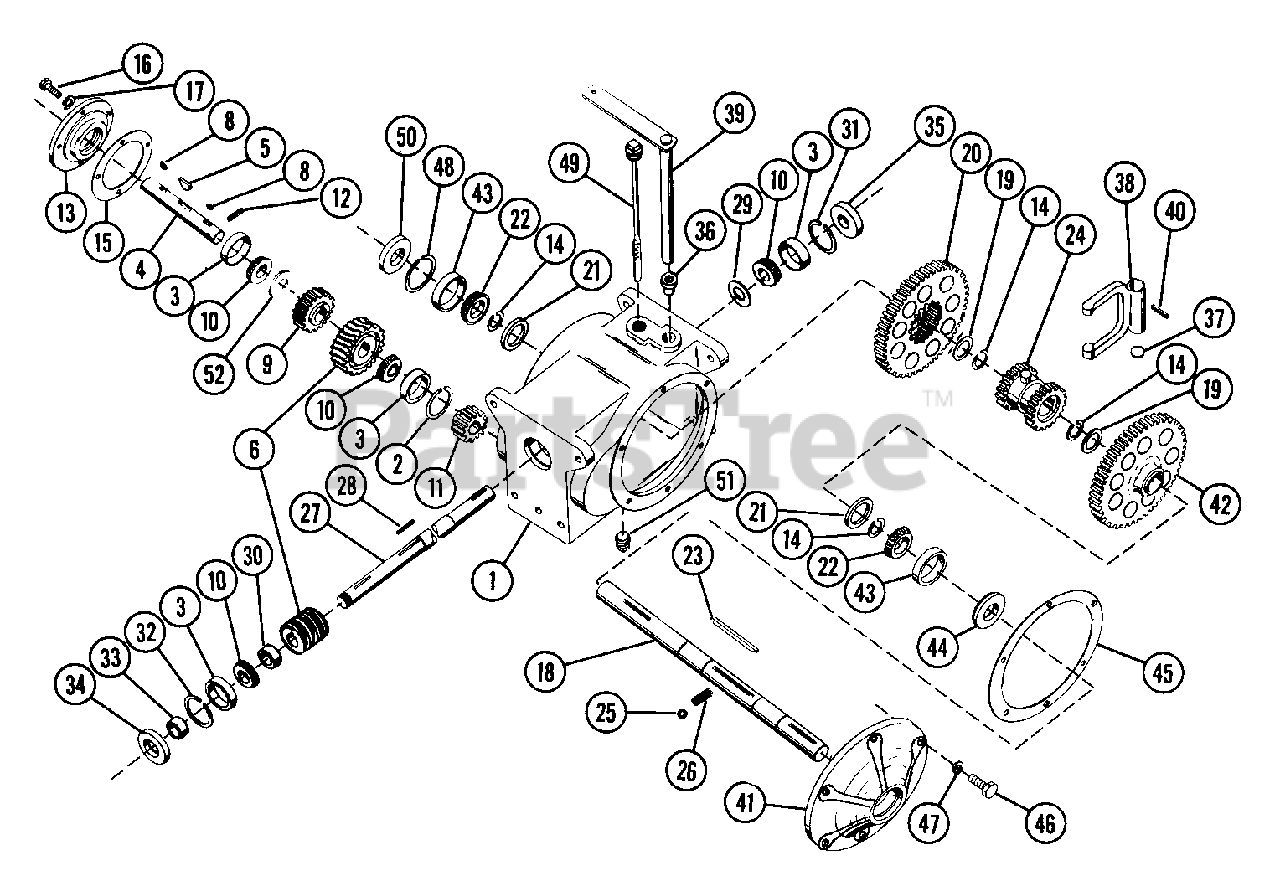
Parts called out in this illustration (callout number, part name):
1	TRANSMISSION CASE
2	RG-RTNG-INT 1.781X.062
3	BRG-CUP 1.781X.475
4	PINION SHAFT
5	KEY-WDRF .188X.875X.375 SAE11
6	50100& WORM GEAR ASSEMBLY TRAN
8	KEY-WDRF .188X.75X.313 SAE 9
9	HIGH PINION
10	BRG-CONE .750X.61
11	LOW PINION
12	PIN-ROLL .188X1.00
13	PINION FLANGE
14	RG-RTNG-EXT .984X.062
16	BLT-HEX .31-18X.75 PL GR2
17	WSHR-LK .312X.097 PL HVY
18	AXLE SHAFT
20	HIGH GEAR
21	GEAR SPACER 1.75 X 1.31 X .5
22	BRG-CONE 1.0X.58
23	KEY-FTHR .25X2.75X.25 SAE1035
24	CLUTCH HUB
25	STEEL BALL
26	SG-COMP .047X.31X.593 WLD11
27	WORM SHAFT
28	KEY-SQ .188X1.0X.188 SAE 8630
29	WSHR-FL-STL .755X1.375X.125
30	BSHG, SPCR .755X1.12X.50 PM
31	RG-RTNG-INT 1.781X.052
32	SNAP RING KIT
33	SPACER BUSHING .99 X .75 X .50
34	SEAL 1.000X1.785X.250
35	SEAL .750X1.781X.250
36	BSHG-FLG .625X.813X.750
37	SPACER DISC (USE SCRAP MATRL)
38	SHIFT YOKE
39	HIGH-LOW SHIFT LEVER
40	PIN-ROLL .250X1.00
41	TRANSMISSION FLANGE
42	LOW GEAR
43	BRG-CUP1.980X.420
44	SEAL 1.000X1.785X.250
45	WHEEL GASKET
46	BLT-HEX .31-18X.88 PL GR2
47	WSHR-LK .312X.097 PL HVY
48	SNAP RING KIT
49	DIP STICK
50	SEAL 1.000X1.980X.250
51	PIPE PLUG
52	LOAD RING
